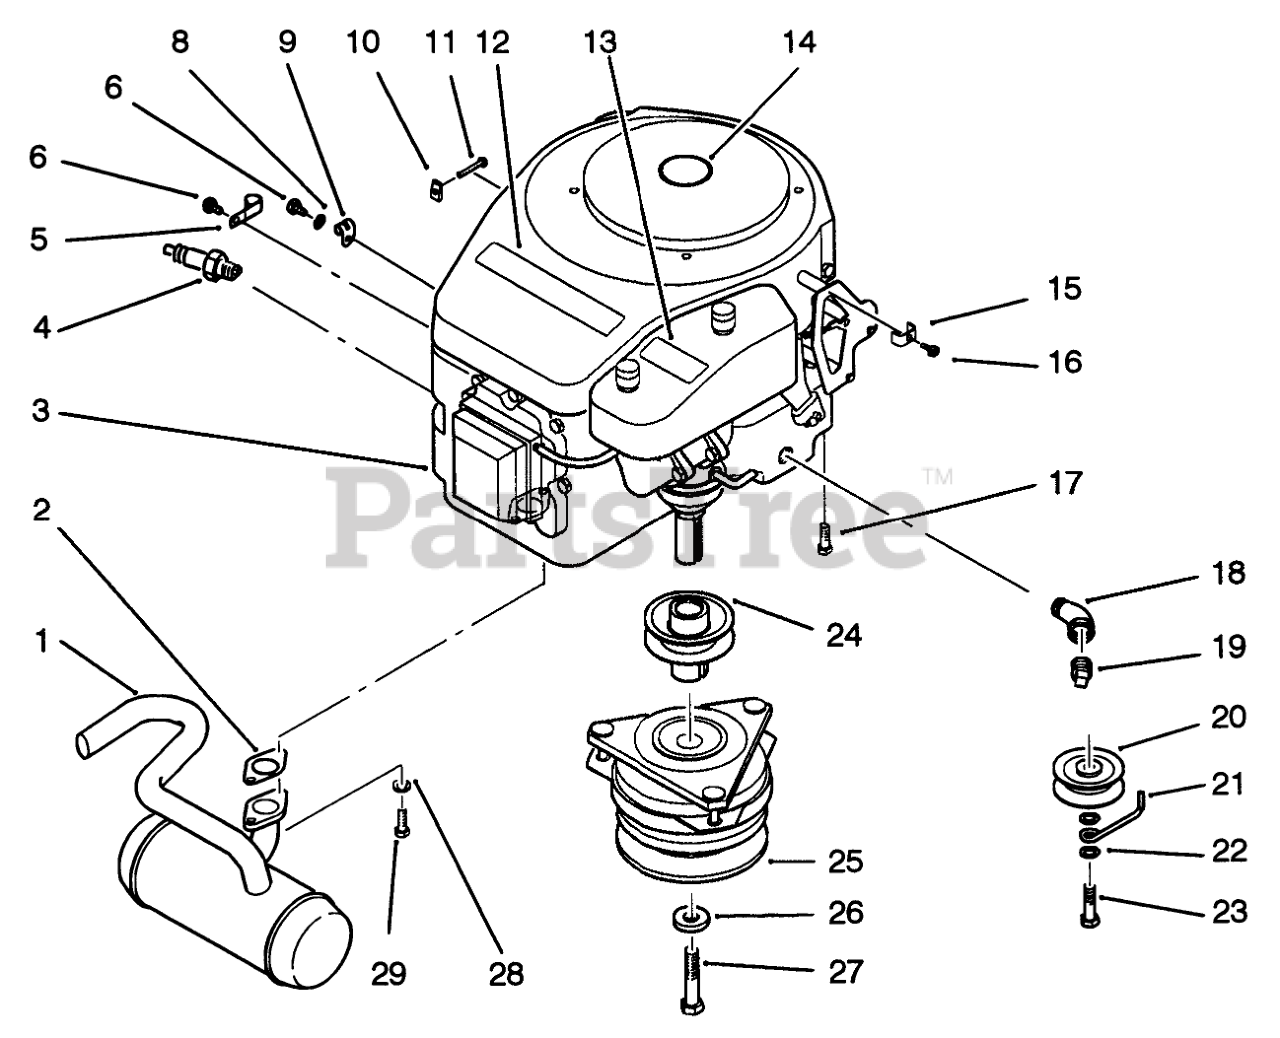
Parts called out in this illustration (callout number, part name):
1	MUFFLER
2	GASKET-EXHAUST
3	ENGINE-E14OV/11207
4	Plug-Spark
5	J-CLIP
6	Screw
8	WASHER-LOCK
9	CLEVIS
10	J-CLIP
11	HHCS M8X1.25X15
12	DECAL-PWR PLUS
13	DECAL-14.0 POWER PLV
14	DECAL-TORO ENGINE
15	Clamp
16	Screw
17	Bolt
18	STREET ELBOW 45DEGRE
19	Plug
20	IDLER PULLEY R
21	GUIDE-BELT
22	WASHER-FLAT
23	Bolt
24	PULLEY ENGINE GEA
25	Clutch
26	WASHER
27	HHCS-M10X1.5X110 ESL
28	WASHER-LOCK
29	HHCS M8X1.25X20
